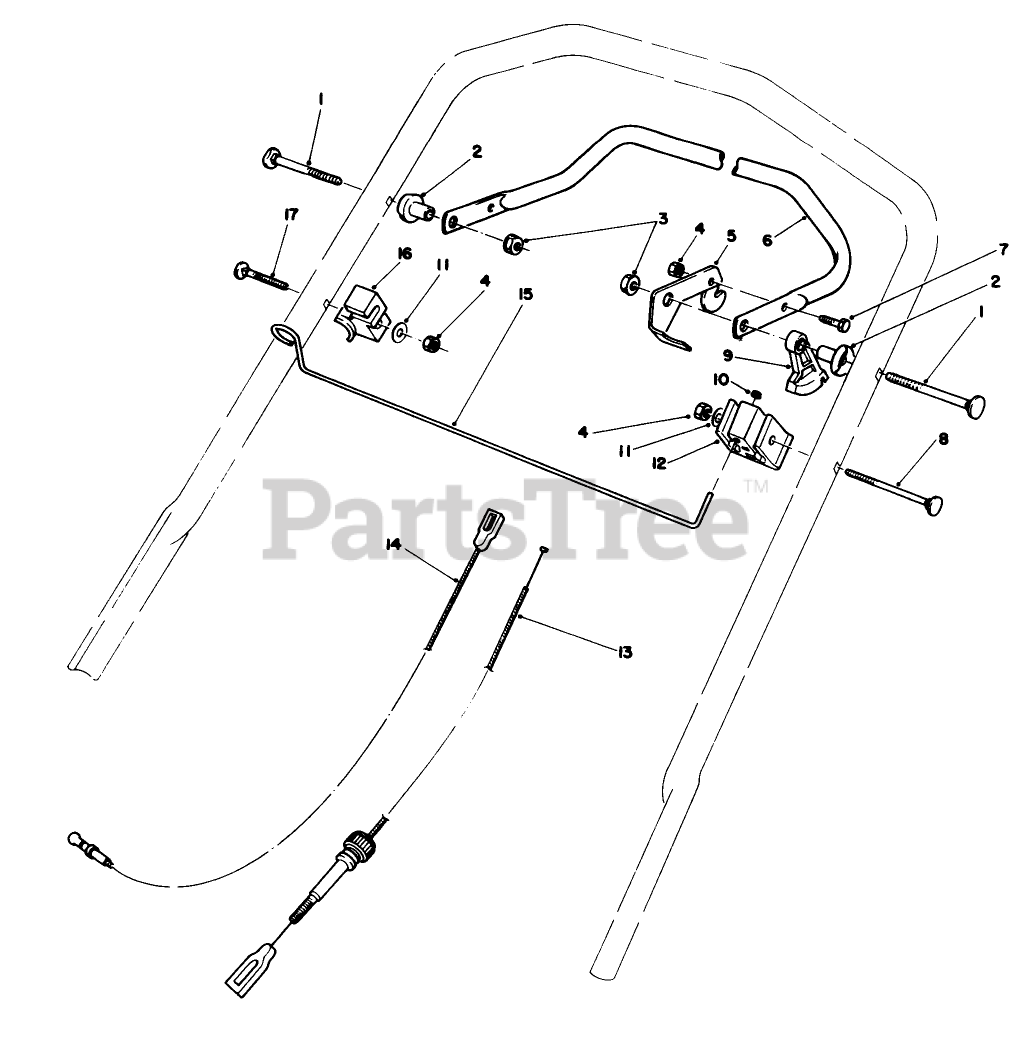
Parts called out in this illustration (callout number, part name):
2	SPACER-SUPPORT
3	NUT-LOCK, NI
4	NUT-LOCK, NI
7	SCREW-HH
8	HANDLE SCREW
9	LEVER-TRACTION
10	NUT-SPEED
11	WASHER-FLAT
12	SUPPORT-CABLE
13	CABLE-TRACTION
14	BRAKE CABLE
16	ROD CATCH
17	SCREW-HANDLE
